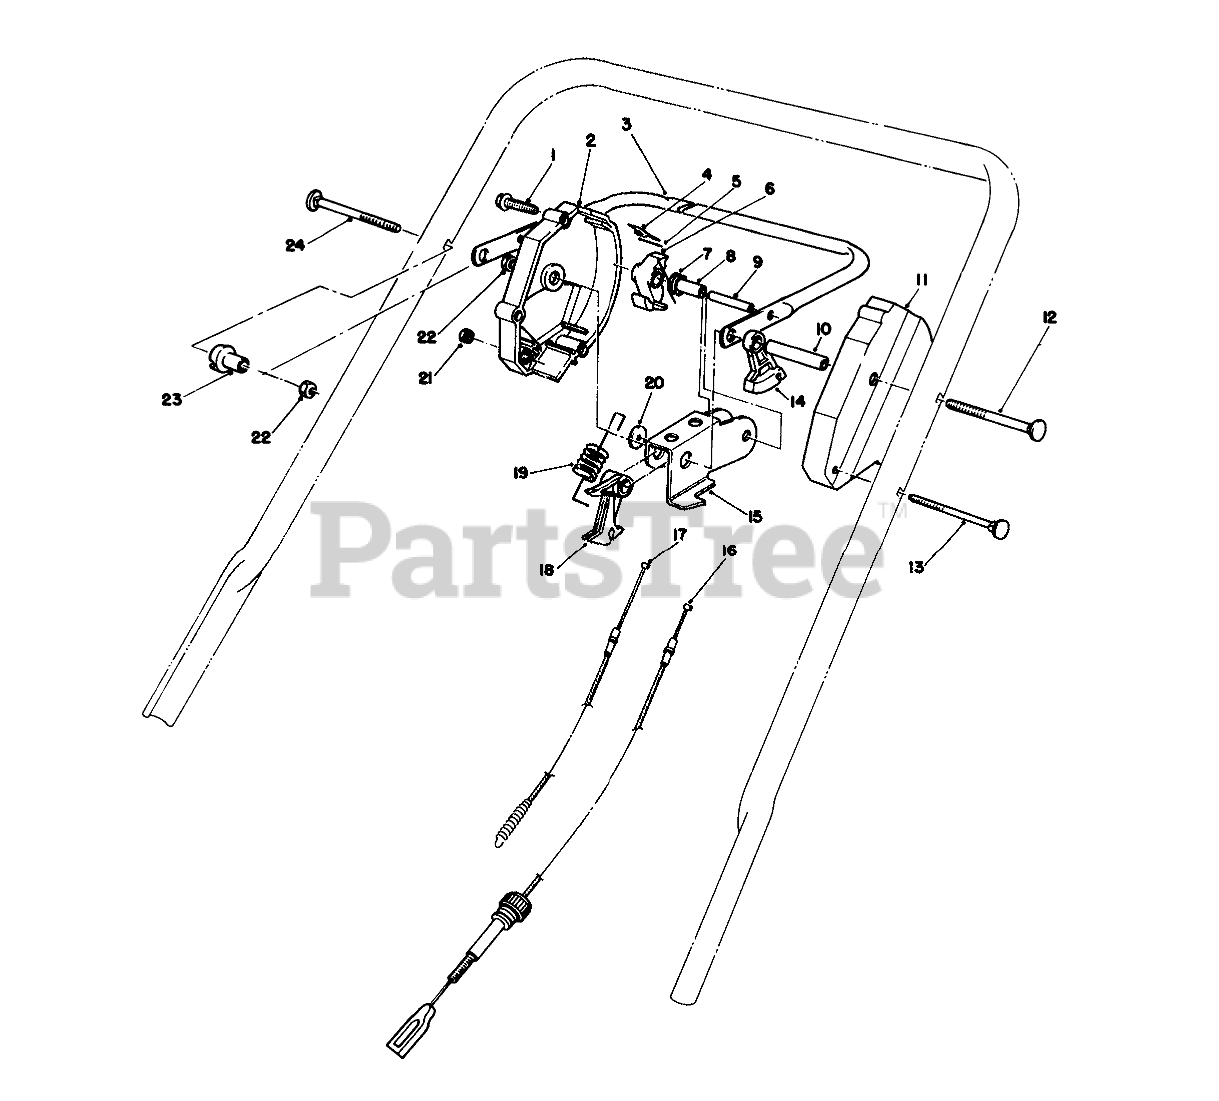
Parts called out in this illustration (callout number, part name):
1	SCREW-HWHTF
2	Housing-Control R.H. (Incl. Ref. #4 & 5)
3	Bar-Control
4	SPRING-LEAF
5	PIN-INSERT
6	HOOK-CONTROL
7	SPRING-TORSION
8	SPACER
9	PIN-ROLL, SLOTTED
10	TUBING-SPACER
11	HOUSING-CONTROL, LH
12	5/16-18 X 3 HNDLE SCREW
13	HANDLE SCREW
14	LEVER-TRACTION
15	ROCKER
16	TRACTION CABLE
17	Cable-Clutch
18	LEVER-CABLE
19	DETENT SPRING
20	PLASTIC WASHER
21	NUT-HEX
22	NUT-LOCK, NI
23	SPACER-SUPPORT
24	5/16-18 X 2 HNDLE SCREW
